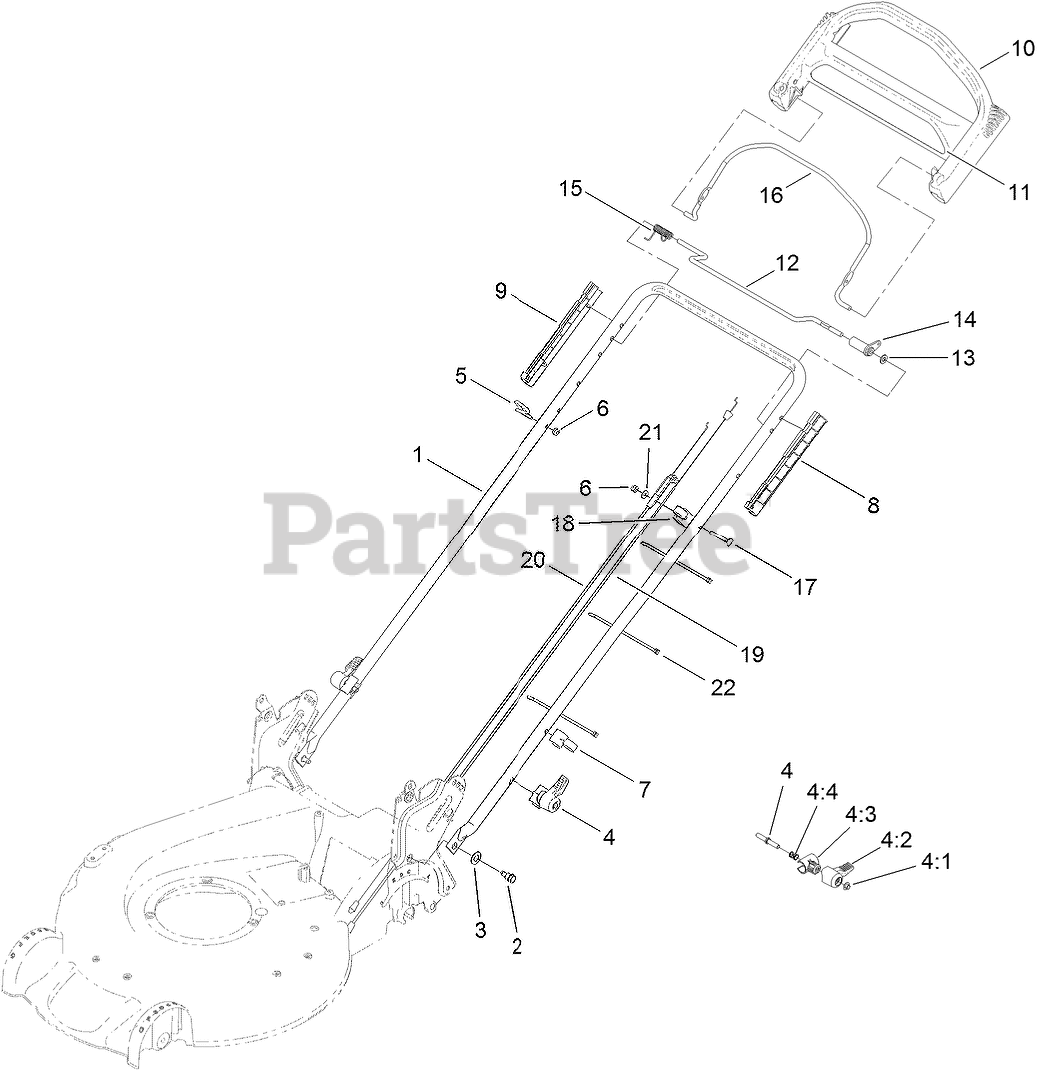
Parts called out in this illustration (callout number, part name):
1	HANDLE
2	BOLT-SHOULDER
3	WASHER-SPRING, CONICAL
4	QUICK RELEASE ASM
4:1	NUT-PUSH
4:2	LEVER
4:3	ANCHOR-SPRING
4:4	SPRING-COMPRESSION
5	GUIDE-ROPE
6	NUT-LOCK, NI
7	GUIDE-CABLE
8	GUIDE-LH
9	GUIDE-RH
10	HANDLE-CONTROL
11	DECAL-HANDLE
12	BAR-CONTROL, TRACTION
13	WASHER-PLAIN
14	LEVER-TRACTION
15	Spring-Torsion
16	Bail-Brake
17	SCREW
18	ANCHOR-CABLE
19	CABLE-TRACTION
20	CABLE-BRAKE
21	WASHER-FLAT
22	TIE-CABLE
